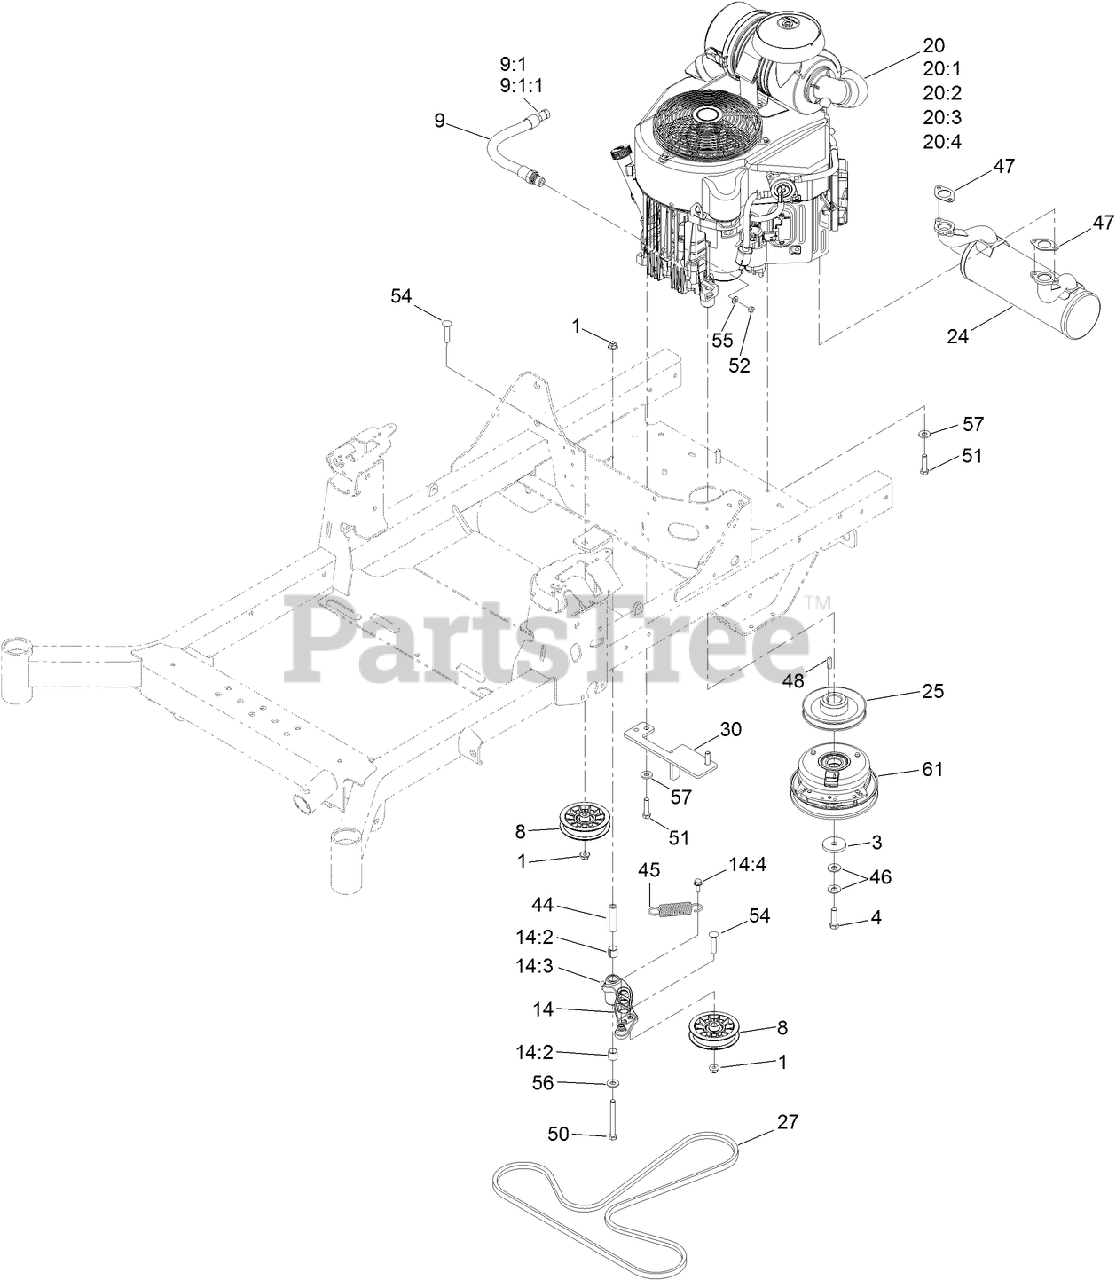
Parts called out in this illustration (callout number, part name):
1	NUT-HF, NI
3	WASHER-CLUTCH
4	SCREW-HH, W/LOCTITE
8	PULLEY-FLAT IDLER
9	ENGINE OIL DRAIN HOSE ASM
9:1	PLUG-HH
9:1:1	O-RING
14	IDLER ARM ASM
14:2	SLEEVE-BEARING
14:3	FITTING-GREASE, 90 DEG
14:4	SCREW-THD ROLL, HWH
20:1	KAWASAKI 49065-7007 ENGINE OIL FILTER
20:2	KAWASAKI 49019-7005 FUEL FILTER
20:3	KAWASAKI 11013-7045 SAFETY FILTER
20:4	KAWASAKI 11013-7044 ENGINE AIR FILTER
24	MUFFLER
25	SHEAVE (W/HUB)
27	BELT-V
30	ANCHOR-CLUTCH
44	BUSHING-PIVOT, IDLER
45	SPRING-EXTENSION
46	WASHER-SPRING
47	GASKET-EXHAUST
50	SCREW-HH
51	SCREW-HH
52	NUT-HEX
54	SCREW-CARR
55	WASHER-FLAT
56	WASHER-FLAT
57	WASHER-BELLEVILLE
61	CLUTCH
